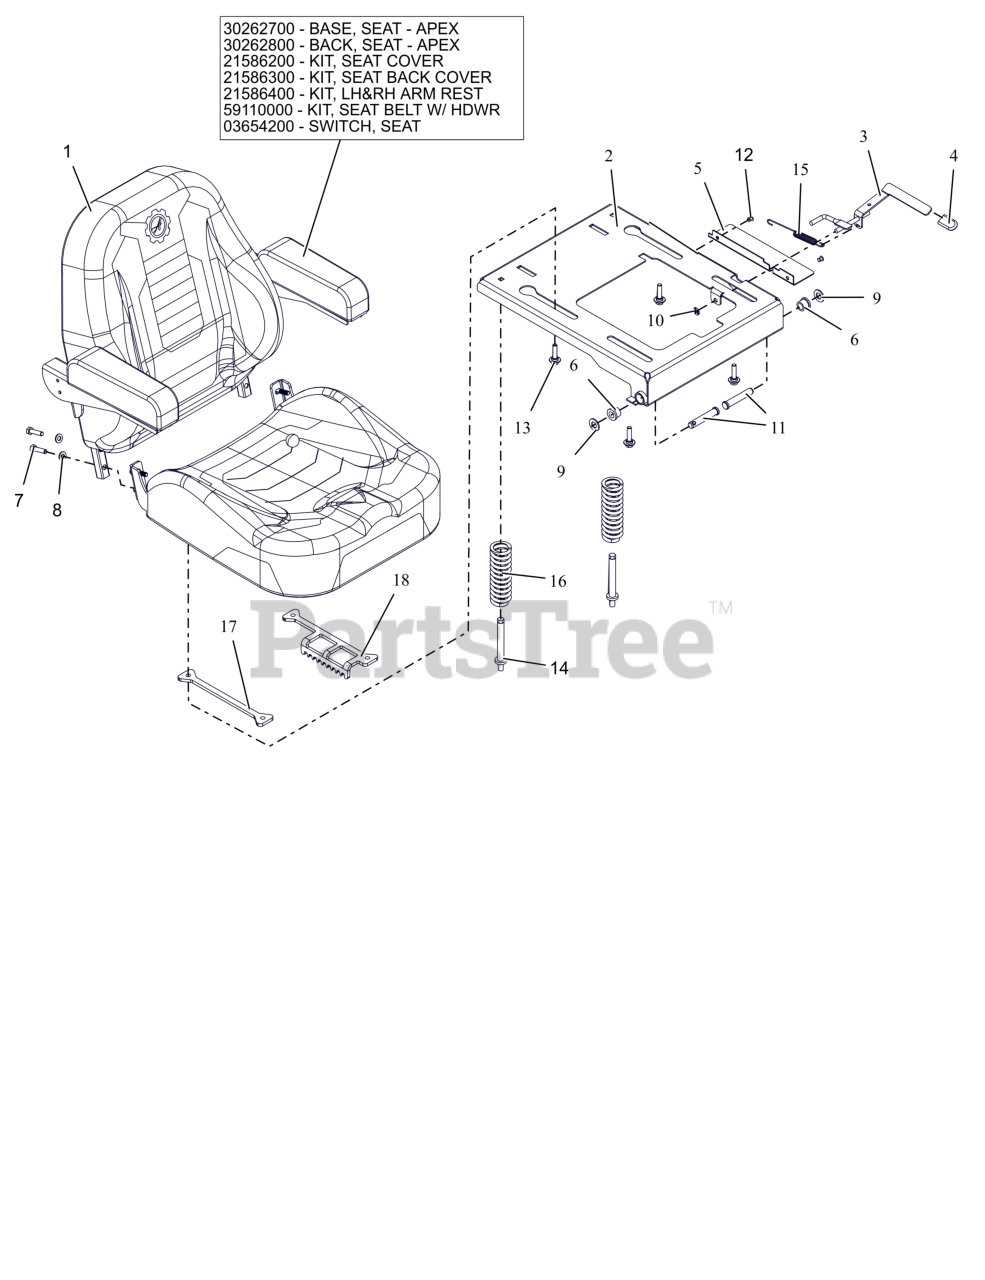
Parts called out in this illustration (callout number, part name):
1	SEAT, ASM APEX/ZENITH
2	WLDMT, SEAT PLATE HD
3	WLDMT, SEAT SLIDE LEVER
3	BASE, SEAT - APEX
3	BACK, SEAT - APEX
3	KIT, SEAT COVER BOTTOM
3	KIT, SEAT BACK COVER
3	KIT, LH & RH ARM REST
3	KIT-SEAT BELT REPLACE-05007300
3	SWITCH- SEAT
4	GRIP, SEAT LEVER, GREY
5	GUARD, SEAT PLATE
6	BSHG, FLG .516X.750X.625X.937
7	BLT, HEX .31-18X1.25 G5 ZCC
8	WSHR,FLT .344X.688X.065 ZCC
9	WSHR-FL-NYL .518X1.000X.080
10	NUT-PUSH .312
11	PIN-CLIC .50X2.70X2.31 -ZCC
12	RVT-POP .187x.250 (#64) BLK
13	BOLT SHLDR .31-18 X .175
14	BOLT, SEAT SPRING
15	SG-TENS .06X.482X5.35
16	SPRING, COMPRESSION SEAT 224LB
17	PLATE, ADJ SEAT SLIDE (BLACK)
18	PLATE, SEAT ADJ (BLACK)
